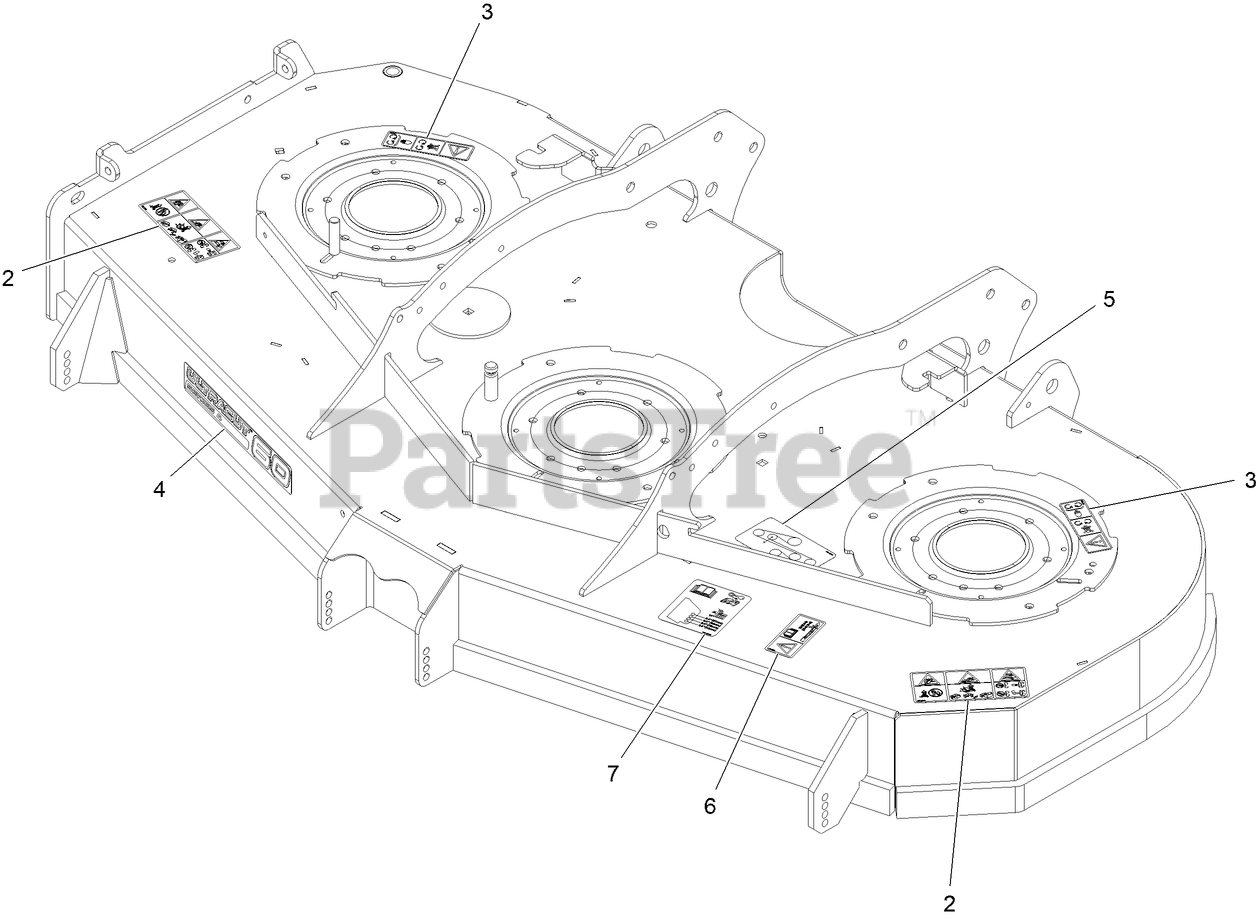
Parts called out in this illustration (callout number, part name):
2	DECAL-WARNING THROWN OBJ
3	DECAL-COVER, MISSING
4	DECAL, 604
5	DECAL-BELT ROUTING
6	DECAL-TORQUE, BOLT
7	DECAL-ROLLER, ANTI-SCALP
